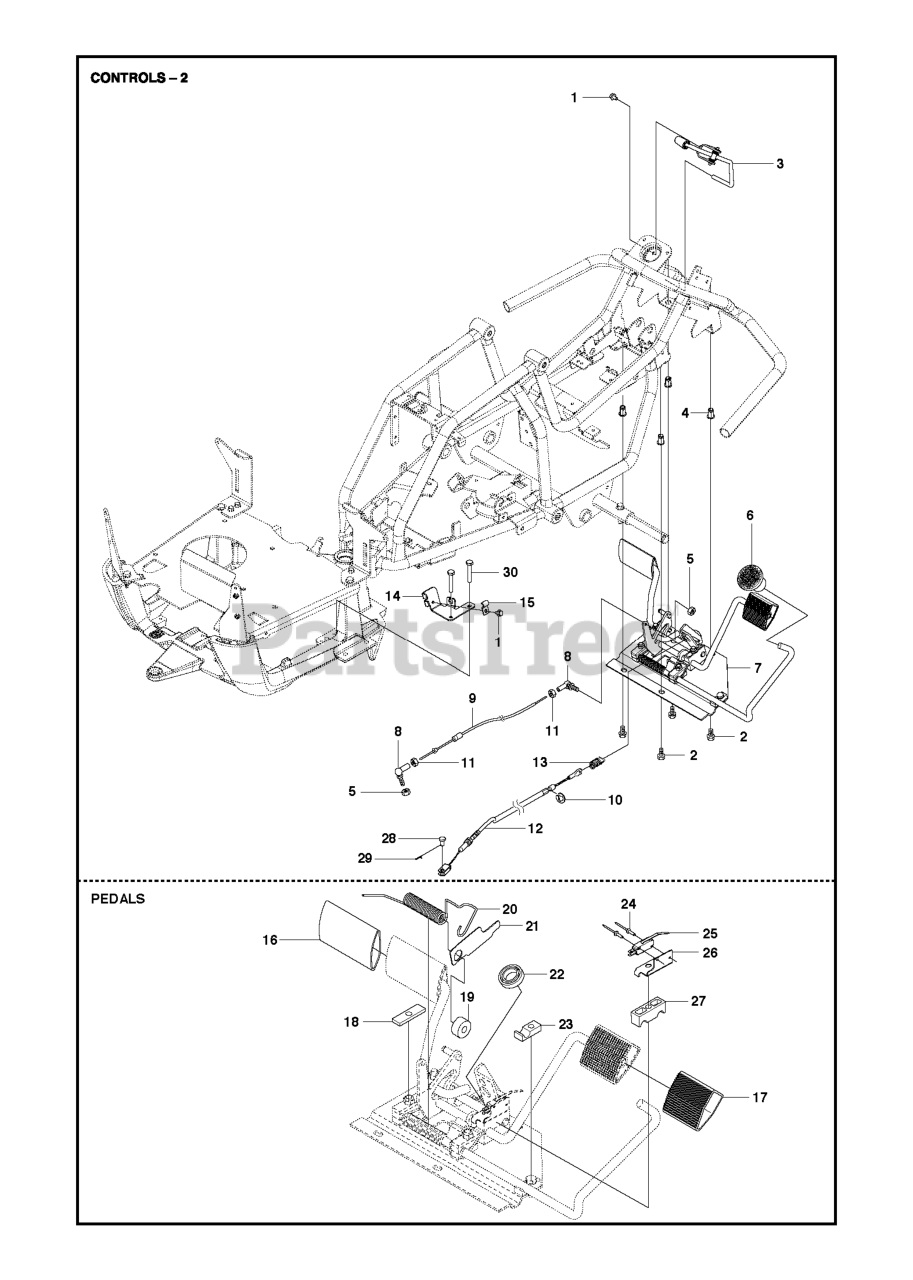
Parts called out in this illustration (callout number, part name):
3	LOCKING LEVER
6	KNOB
8	CONNECTOR
9	CONTROL CABLE
11	LOCKNUT M5
12	BRAKE WIRE
16	PEDAL RUBBER, SF
17	PEDAL RUBBER
18	PLATE
19	ROLLER
20	SPRING
21	PLATE
22	BALL BEARING 6002-2RS1
23	SUPPORT
25	MICRO SWITCH
27	PEDAL SHAFT CLAMP
28	Clevis Pin
29	Cotter Pin
30	BOLT FLANGE - M6X20
